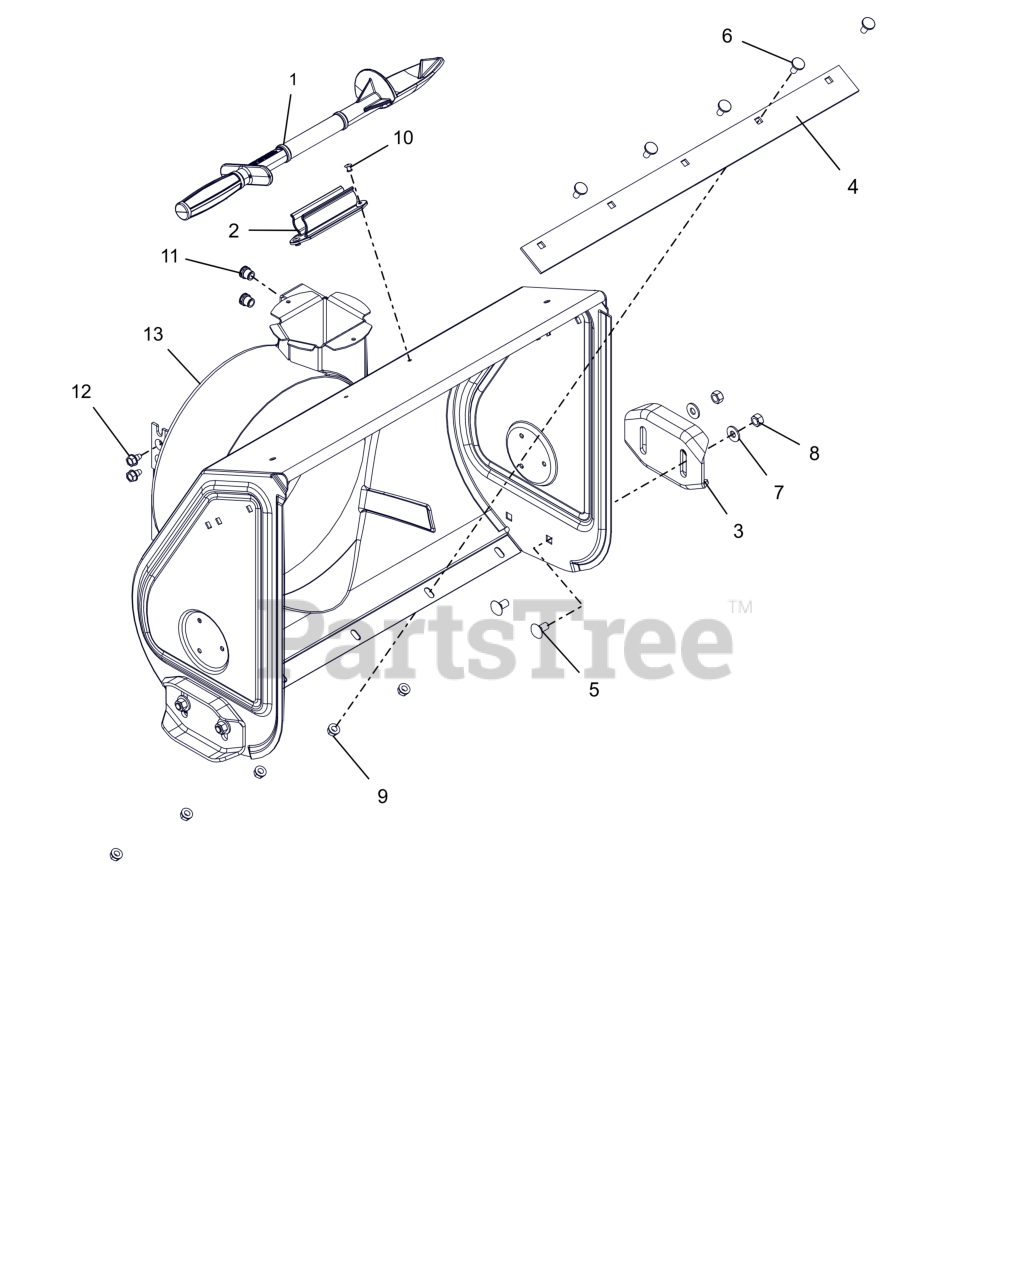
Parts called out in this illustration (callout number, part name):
1	DEVICE, SNOW CLEAN OUT
2	MOUNT, SNOW CLEAN OUT
3	SKID SHOE, REVERSIBLE - ORANGE
4	SCRAPER BLADE, 24" COMPACT HI
5	BLT, RHSSN .38-16X.75 G5 ZCC
6	BOLT, MODIFIED HEAD CARRIAGE
7	WSHR,FLT .375X.875X.083 ZCC
8	NUT-LK-CTR .38-16 ZC120
9	NUT-LK-TOP-FLG .312-18 GF ZCC
10	RVT, POP .1875 ZCC
11	NUT,THD,INSERT .38-16 ZC120
12	SCR,TAP .312-18X.50 HWH TR ZCC
13	BLOWER HOUSING, 24" HI ORANGE
